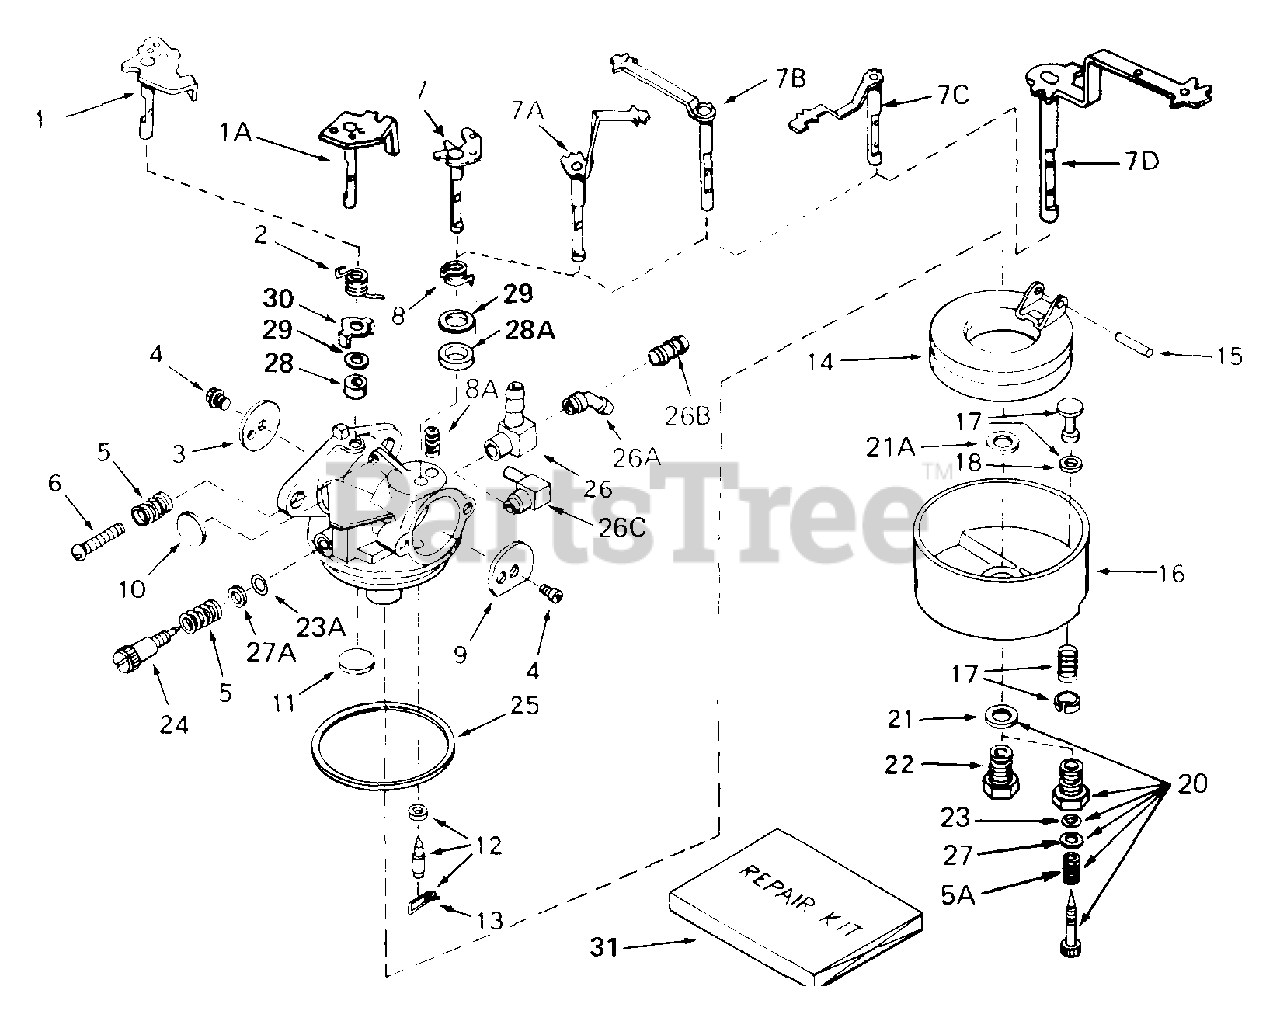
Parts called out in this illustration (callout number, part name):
1	"Shaft & Lever Assy., Throttle
2	Spring, Throttle return
3	Shutter, Throttle
4	Screw, Throttle & Choke shutter
5	Spring, Regulating screw
5A	Spring, Main adj. screw
6	Screw, Regulating screw
7C	Shaft & Lever, Choke
8A	Spring, Choke positioning
9	Shutter, Choke
10	Plug, Welch
11	Plug, Welch
12	Inlet needle, Seat & Clip
13	Clip, Inlet needle
14	Float, Carburetor
15	Shaft, Float
16	Bowl & Drain Assy., Float
17	Plunger Assy., Drain
18	Gasket, Drain plunger
20	Adj. Screw Assy., Main
21	Gasket, Bowl-to-body
23	"O" Ring, Adj. screw
23A	"O" Ring, Adj. screw
24	Screw, Idle adj
25	Gasket, Bowl-to-body
26A	Fitting, Fuel inlet
31	Repair Kit
